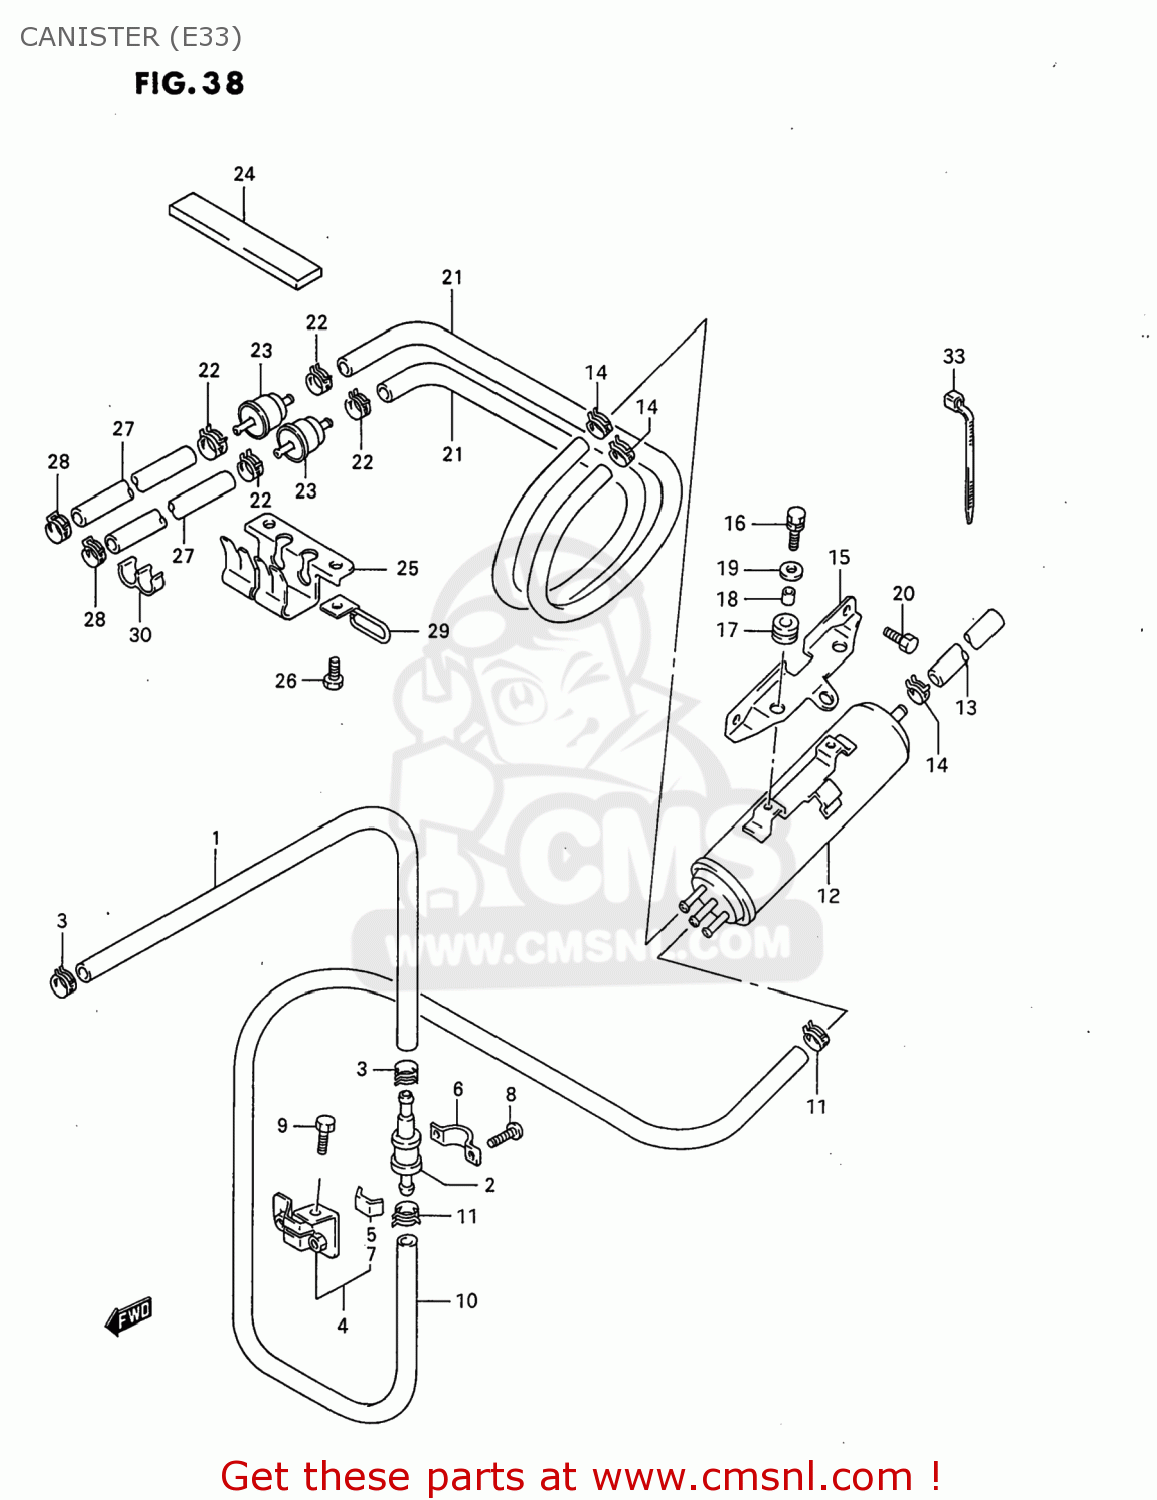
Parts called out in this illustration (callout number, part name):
1	HOSE(5.4X11.4X2000)
2	VALVE,FUEL TANK BREATHER
3	CLIP
4	BRACKET COMP,TANK BREATHER
5	CUSHION
6	PLATE,FUEL TANK BREATHER NO.2
7	CUSHION
8	SCREW
9	BOLT
10	HOSE,BREATHER VALVE & CANISTER
11	CLIP
12	CANISTER ASSEMBLY,CHARCOAL
13	HOSE(7X12X600)
14	CLIP
15	BRACKET,CANISTER MOUNT
16	BOLT
17	CUSHION
18	SPACER(6.1X9X7.5)
19	WASHER(6.5X22X1.6)
20	BOLT
21	HOSE(5.4X11.4X600)
22	CLIP
23	VALVE,CANISTER PURGE
24	CUSHION,COVER SIDE
25	HOLDER,CPV
26	BOLT
27	HOSE(5.4X11.4X600)
28	CLIP
29	GUIDE,HOSE
30	CLAMP
